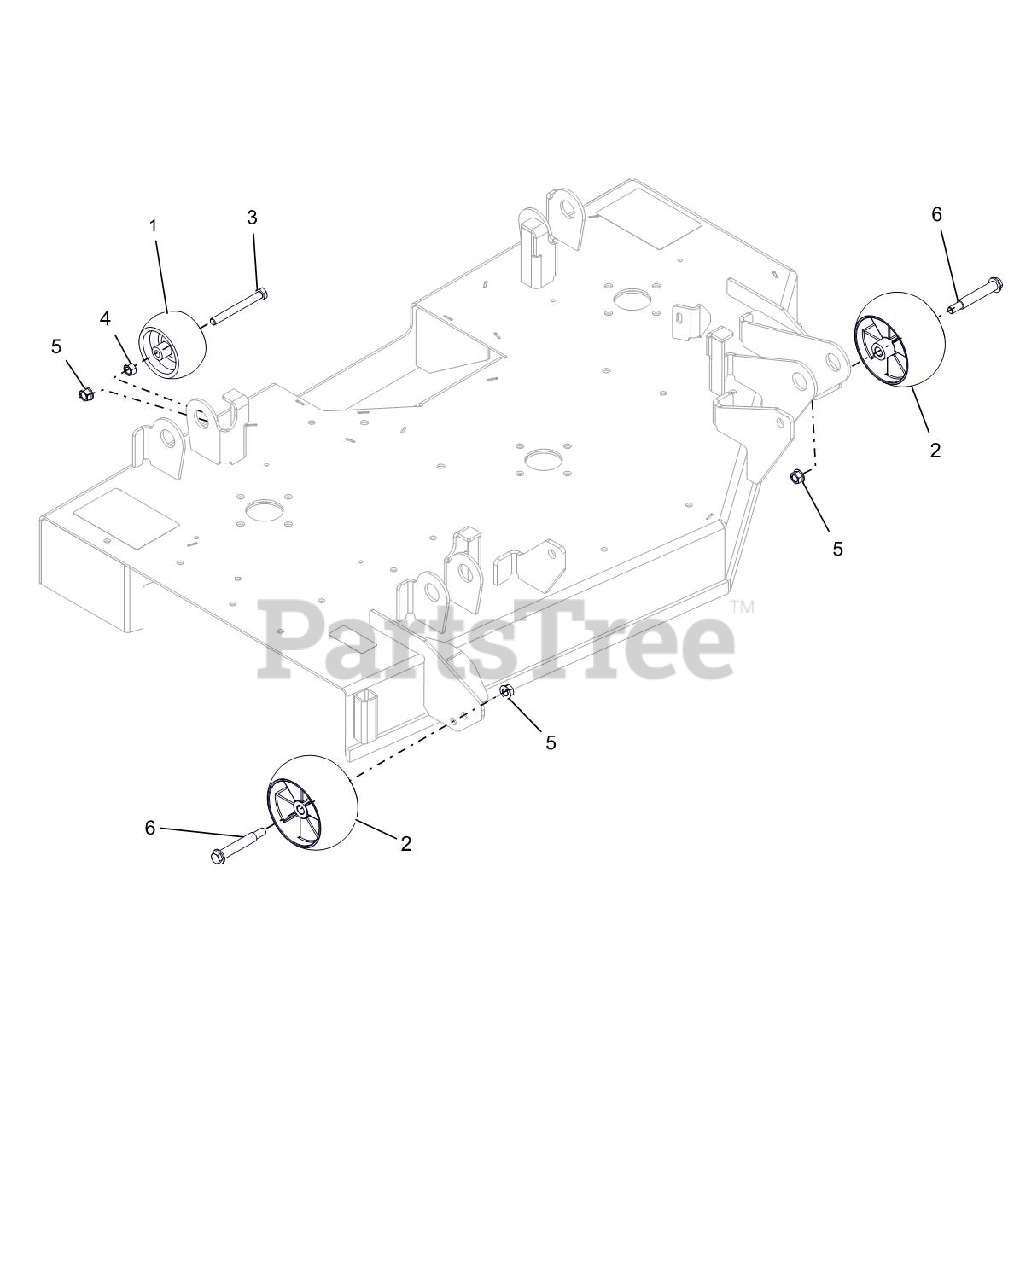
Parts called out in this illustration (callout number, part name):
2	ANTI-SCALP WHEEL - 5X OS
3	@BLT-HEX .38-16X3.50 GR5 YWZC
4	@NUT-HEX .38-16 YWZC
5	@NUT-LK-TOP-FLG .38-16 YWZC
6	BLT-SHLDR .38-16X2.50 HWH G5
